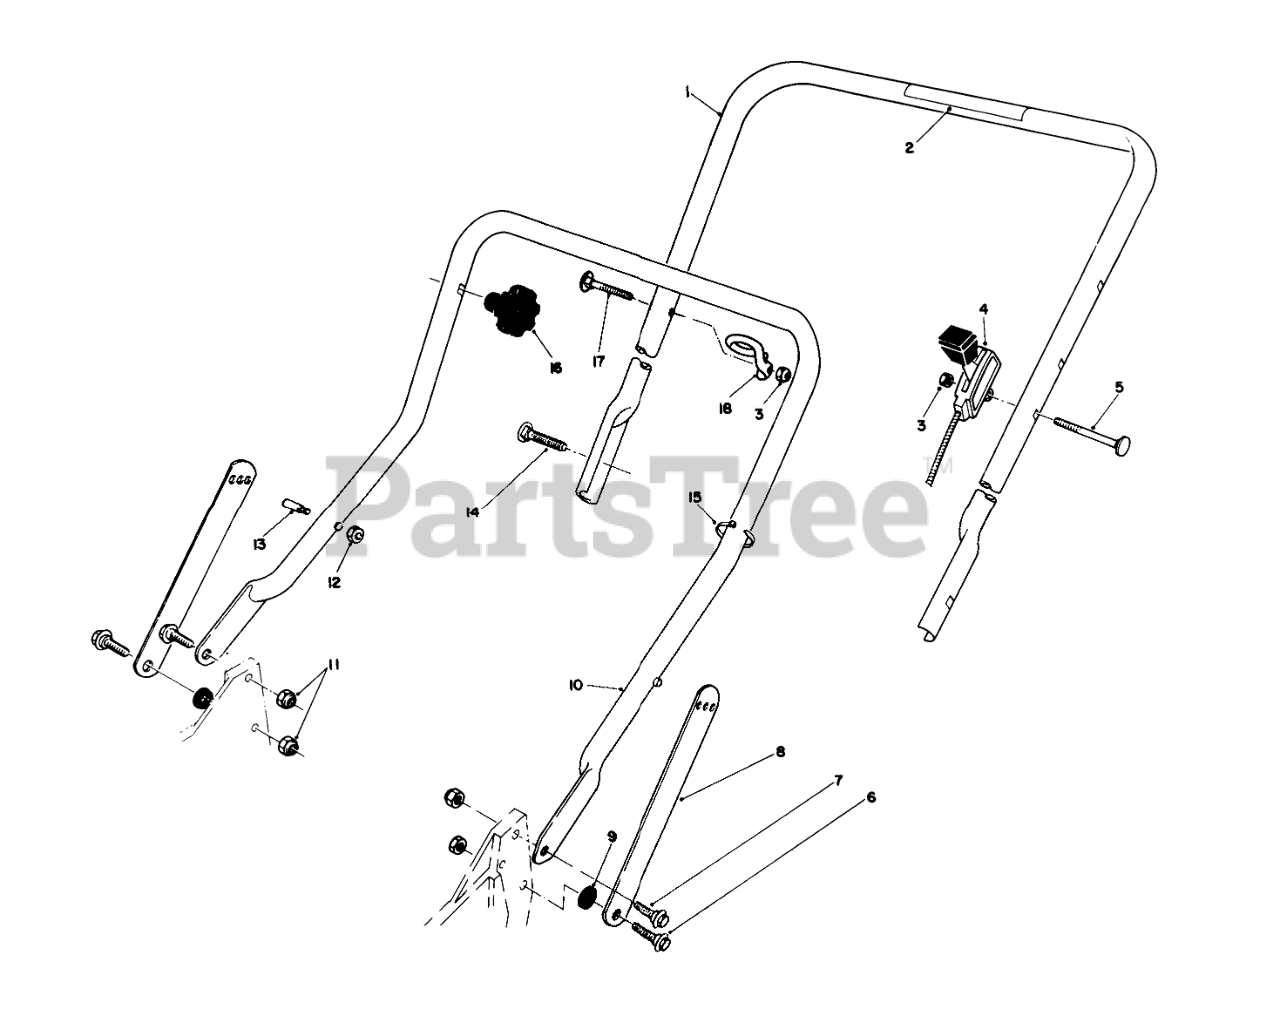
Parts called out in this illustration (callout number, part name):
1	Handle-Upper (Incl. Ref. #2)
2	DECAL - HANDLE
3	NUT-LOCK, NI
4	THROTTLE CONTROL
5	SCREW-HANDLE
6	SCREW-SHOULDER
7	SCREW-SHOULDER
8	Handle Latch
9	SPACER
10	LOWER HANDLE ASM
11	NUT-LOCK, NI
12	NUT-LOCK, NI
13	HANDLE PIN
14	5/16-18 X 2 HNDLE SCREW
15	TIE-CABLE
17	HANDLE SCREW
18	Guide
